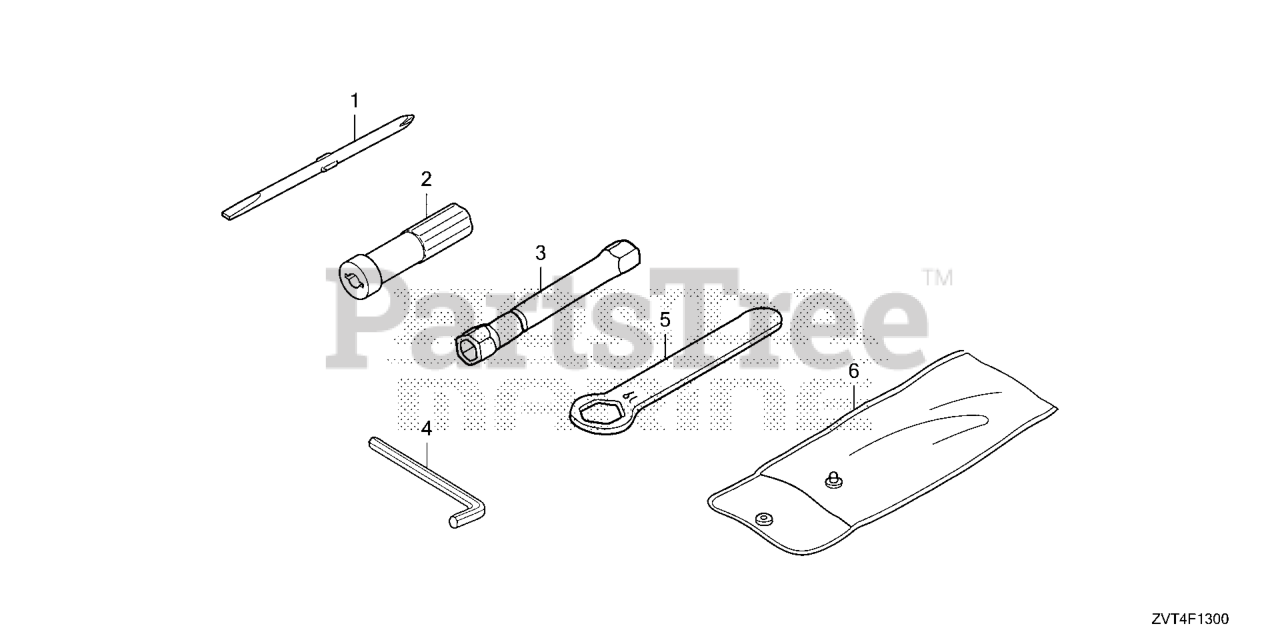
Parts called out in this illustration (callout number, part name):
1	SCREWDRIVER (NO.2 PHILLIPS -)
3	WRENCH, PLUG
4	WRENCH, HEX. (6MM)
5	WRENCH, EYE (19MM)
6	BAG, TOOL (230MM)
